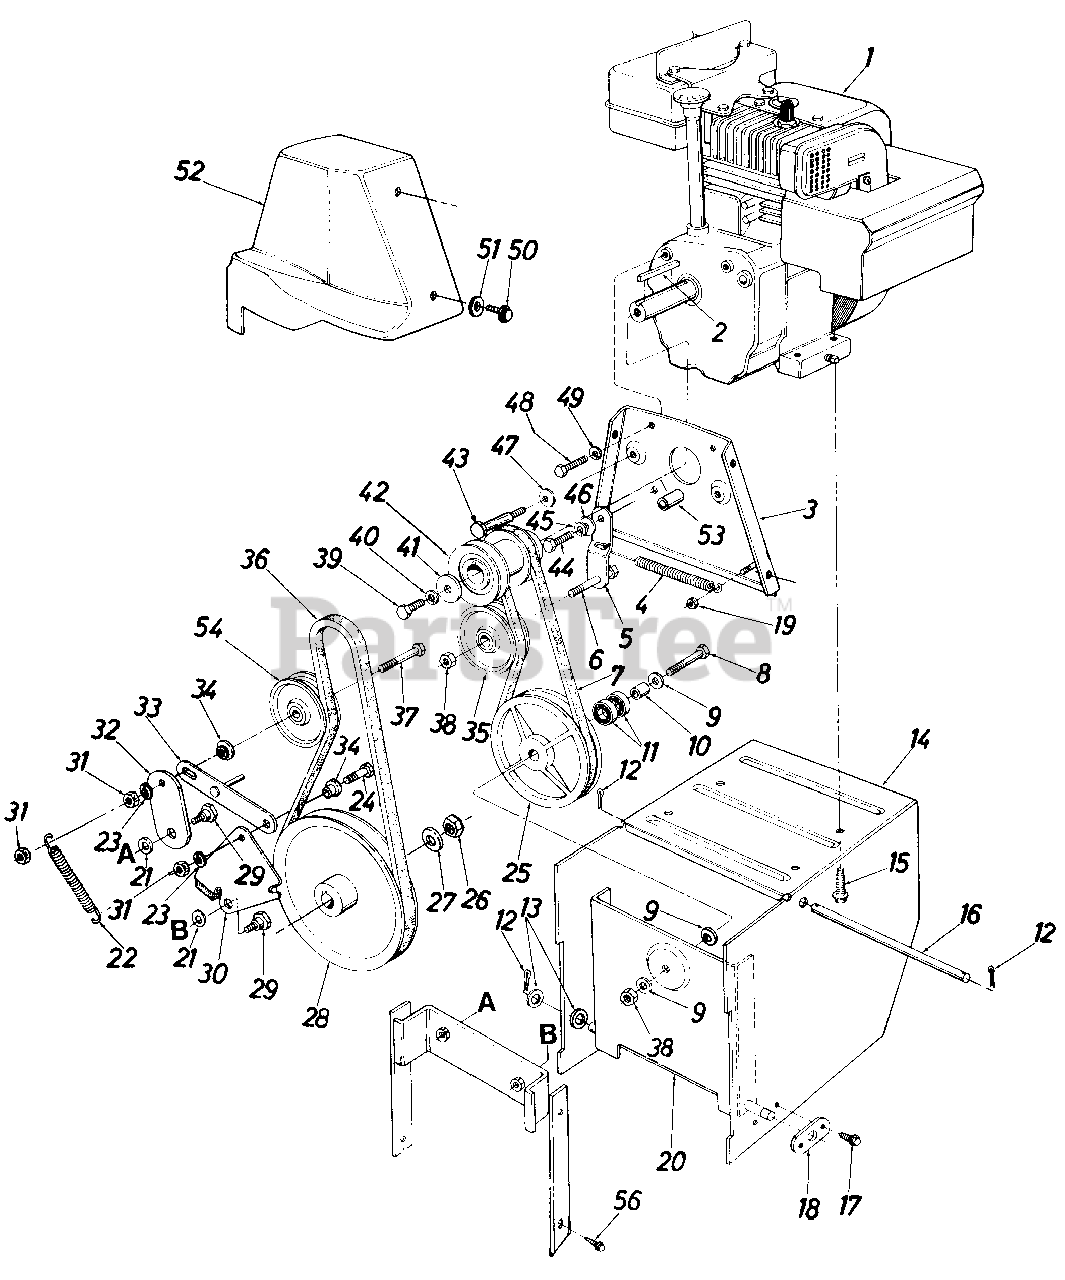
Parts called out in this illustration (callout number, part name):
1	Engine
2	Sq. Key 3/16" x 1.50" Lg.
3	Engine Plate Ass'y.
4	Extension Spring .50" O.D. x 3.97" Lg.
5	Drive Clutch Idler Brkt.
6	Hex Bolt 3/8-24 x 1.25 Lg.*
7	"V"-Belt 3/8" x 29.0" Lg.
8	Hex Bolt 3/8-24 x 1.50" Lg.
9	Bell-Wash. .40" I.D. x .88" O.D. x .06
10	Spacer .38" I.D. x .62" O.D. x.75" Lg.
11	Ball Brg. .62" I.D. x 1.38" O.D. x .44
12	Cotter Pin 3/32" Dia. x .75" Lg.*
13	Fl-Wash. .53" I.D. x 1.00" O.D. x .125
14	Frame Ass'y.
15	Hex Wash. Hd. Self-Tap Scr. 3/8-16 x 1.25" Lg.
16	Shaft .50" Dia. x 9.50" Lg.
17	Hex Wash. Hd. Self-Tap Scr. 1/4-20 x .50" Lg.
18	Axle Bracket
19	Hex L-Nut 1/4-20 Thd.
20	Drive Pulley Support Brkt. Ass'y.
21	Bell-Wash. .40" I.D. x 1.13" O.D.
22	Extension Spring .56" O.D. x 4" Lg.
23	L-Wash. 3/8" I.D.*
24	Hex Scr. 3/8-16 x 1.25" Lg.
25	6.00" O.D. Drive Pulley Ass'y.
26	Hex Jam Cent. L-Nut 5/8-18 Thd.
27	Fl-Wash. .64" I.D. x .94" O.D. x .06
28	1/2" V-Pulley .625" I.D. x 7.50" O.D.
29	Shld. Bolt .625" Dia. x .170" Lg. (3/8-16)
30	Brake Bracket Ass'y.
31	Hex Ins. L-Nut 3/8-16 Thd.
32	Auger Clutch Idler Brkt.
33	Brake Linkage Ass'y.
34	Shld. Spacer .625" I.D.
35	Fl-Idler Pulley 2.25" O.D.
36	"V"-Belt
37	Hex Bolt 3/8-16 x 2.25" Lg.
38	Hex Ins. Jam L-Nut 3/8-24 Thd.
39	Hex Bolt 3/8-24 x 1.50" Lg.
40	L-Wash. 3/8" I.D.*
41	Fl-Wash. .40" I.D. x 1.25" O.D.
42	Double Groove Engine Pulley
43	Shld. Scr. .498" x 3.0" Lg.
44	Hex Bolt 5/16-24 x 1.00" Lg.
45	L-Wash. 5/16" I.D.*
46	Shld. Spacer .320" I.D.
47	Bell-Wash. .40" I.D. x .88" x .06
48	Hex Bolt 5/16-24 x .62" Lg.
49	L-Wash. 5/16" I.D.*
50	Hex Wash. Hd. Self-Tap Scr. 1/4-20 x .50" Lg .
51	Fl-Wash. .28" I.D. x .75" O.D. x .06
54	Fl-Idler Pulley 2.75" O.D.
56	Hex Wash. Hd. Self-tap Scr. 3/8-16 x .75" Lg.
